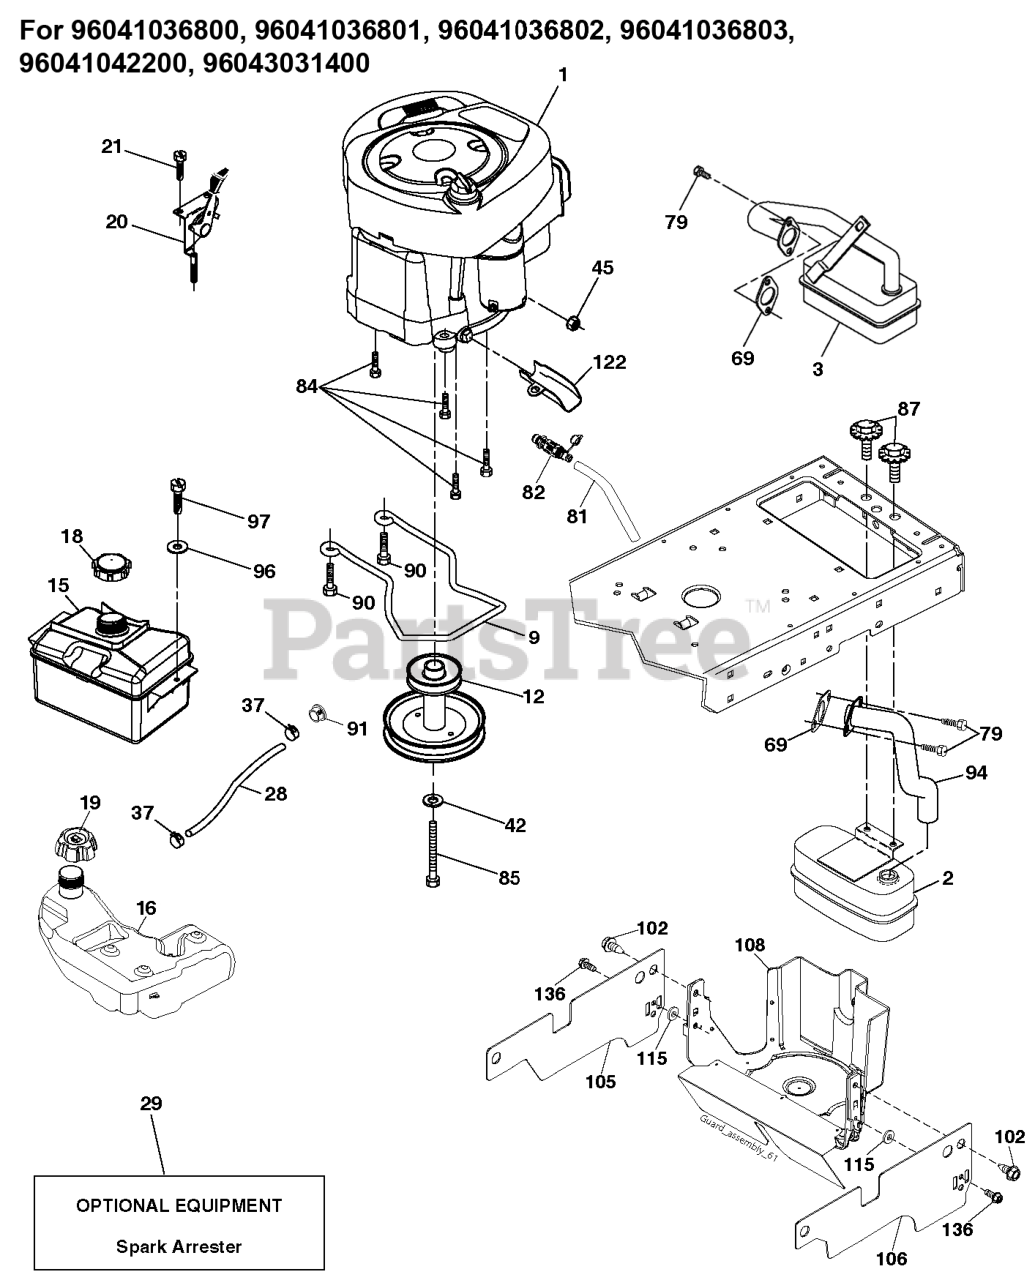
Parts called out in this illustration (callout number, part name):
2	MUFFLER.SINGLE.CYL.KOHL/B&S
2	MUFFLER.ASM.SINGLE
3	MUFFLER.LT.BRIGGS.14HP.IC/OHV
9	KEEPER.BELT.ENG.4.25"2.BLT.431
12	ENGINE.PULLEY
15	FUEL.TANK.ASM.NON-EPA
16	FUEL TANKS
18	FUEL CAP
18	CAP.2.25'.VENTED.RATCHET.EPA
19	CAP ASSY FUEL 3" GRAY
20	THROTTLE.COBRA.21".RSTART.BLK
20	THROTTLE CABLE
28	LINE.FUEL.64"REAR.EMIS
28	HOSE 1/4" LOW PERMEATION FUEL
29	KIT.SPARK ARRESTOR 794945 B&S
37	HOSE CLAMP
45	Hardware
45	NUT HEX_LRG FLG_1_4-20_LOCK
69	REPL BY 532 27 22-93
81	TUBE, DRAIN OIL ASM.
82	VALUE.OIL.DRAIN
84	SCREW.3/8-16
85	BOLT.HEX.7/16-20X4.GR5.1.5BLUE
87	BOLT.5/16-18UNCX3/4 W/SEMS.BLK
90	SCREW 3/8-16X1
91	BUSHING.1.375OD
94	EXHAUST.TUBE.B&S.28/31
96	WASHER
97	SCREW HEXWSHR 1/4-20X3/4
102	SCREW
105	SHIELD.SIDE.LH.3842"TEX FRN.BK
106	SHIELD.SIDE.LH.3842"TEX FRN.BK
108	COVER ENGINE PULLEY COVER WITH
115	RETAINER
122	EXTENSION DRAIN OIL
136	SCREW.#10 X 0.500
